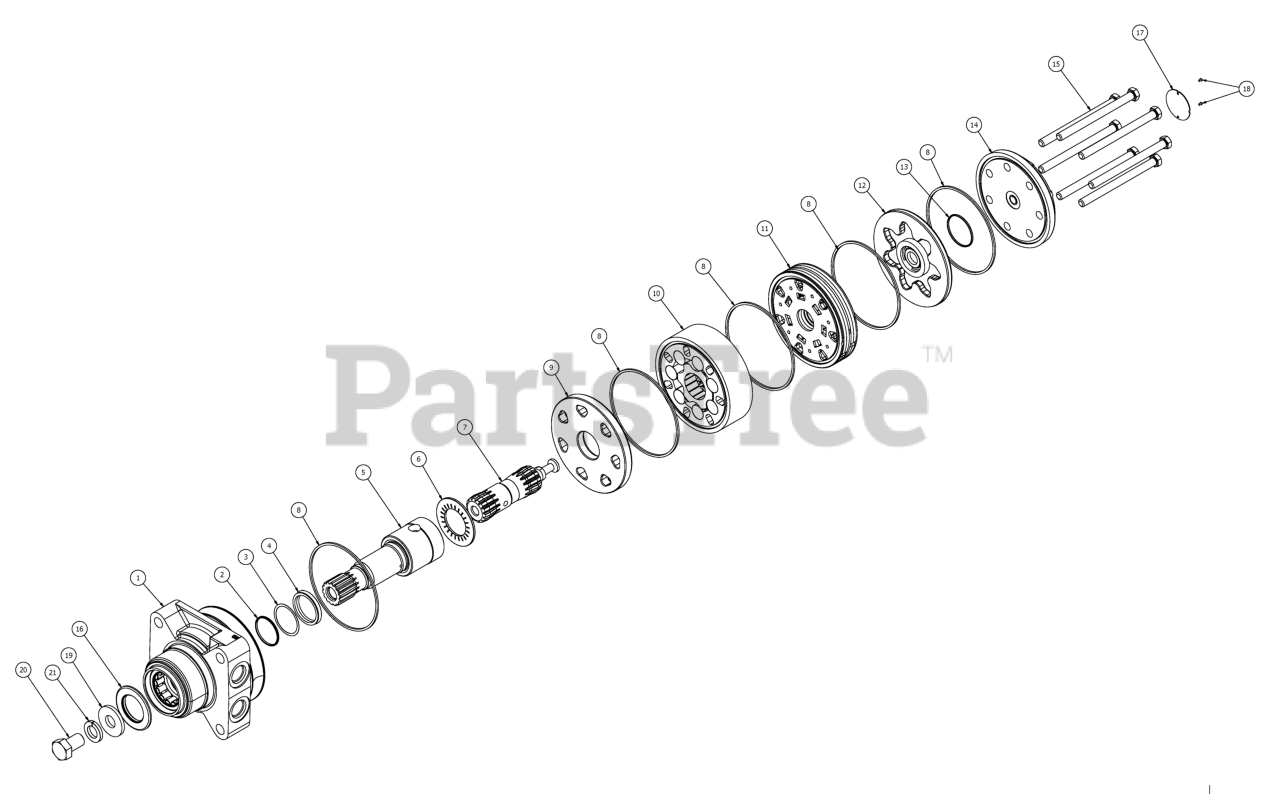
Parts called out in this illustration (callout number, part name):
1	ASSY, HOUSING
2	BACK UP RING
3	BACK UP WASHER
4	SHAFT SEAL
5	SHAFT, COUPLING
6	THRUST BEARING
7	LINK, DRIVE
8	SEAL RING
9	WEAR PLATE
10	CHART, ROTOR ASSY
11	MANIFOLD (CW)
12	COMMUTATOR ASSM
13	COMMUTATOR SEAL
14	END COVER
15	BOLT, MOTOR ASSY
16	DIRT AND WATER SEAL
17	IDENTIFICATION TAG
NS	SEAL KIT
